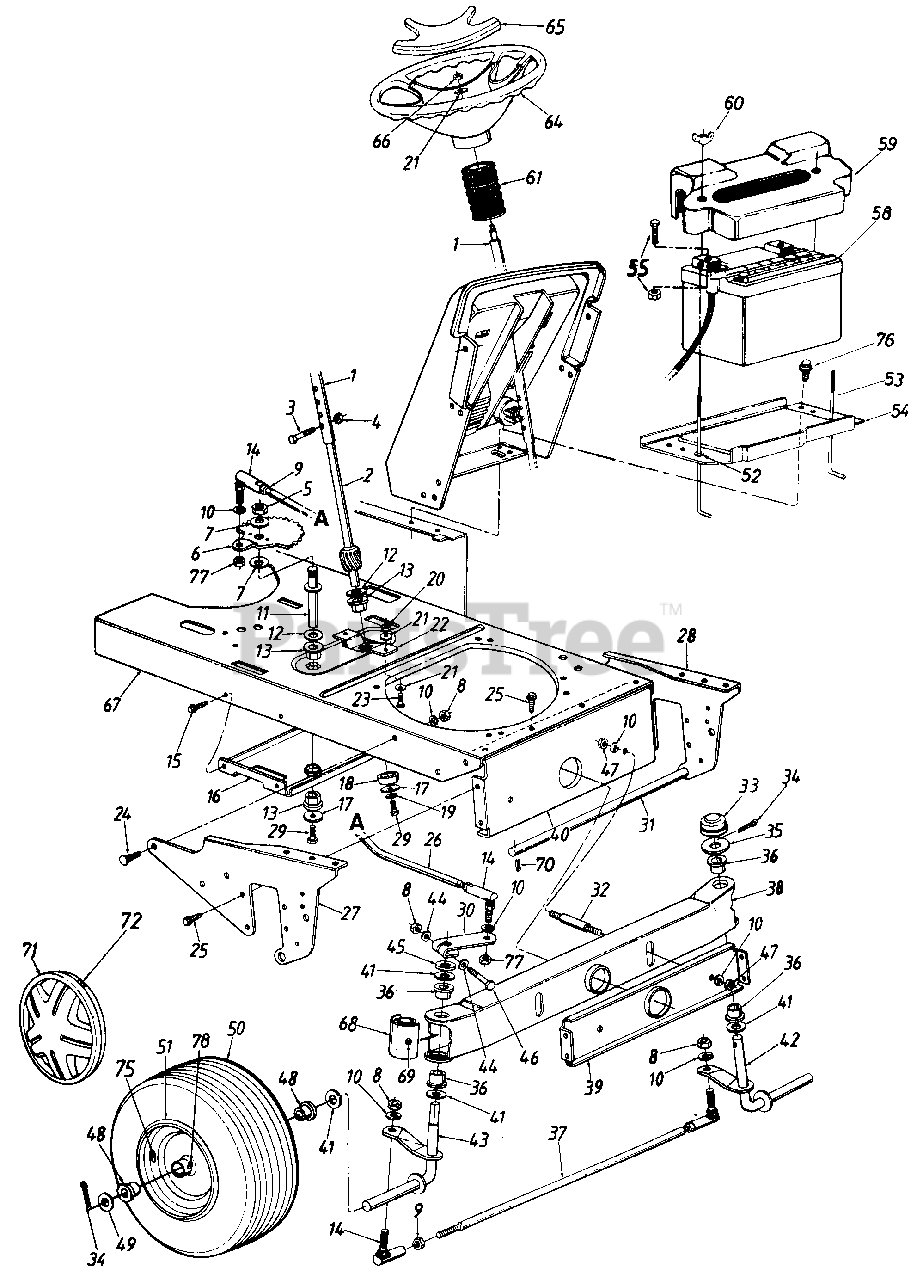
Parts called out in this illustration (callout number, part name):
1	Steering Column Ass'y.
2	Lower Steering Shaft
3	Hex Bolt 1/4-20 x 1.31" Lg.
4	Hex L-Nut 1/4-20 Thd.
5	Hex Nut 5/8-18 Thd.
6	Steering Gear Segment
7	Bell-Wash. 5/8" I.D. x 1.25" O.D.
8	Hex Nut 3/8-24 Thd.
9	Hex Jam Nut 3/8-24 Thd.
10	L-Wash. 3/8" I.D.
11	Steering Gear Segment Shaft
12	Fl-Wash. .64" I.D. x 1.24" O.D.
13	Hex Flange Brg. .63" I.D.
14	Ball Joint Ass'y.
15	Hex Wash. Hd. TT-Tap Scr. 1/4-20 x .5" Lg.
16	Deck Idler Support Brkt.
17	Fl-Wash. .33" I.D. x 1.25" O.D.
18	Spacer .985" I.D. x 1.25" O.D.
19	L-Wash. 5/16" I.D.
20	Hex Nut 5/16-24 Thd.
21	Bell-Wash. .345" I.D. x .88" O.D.
24	Ribbed Neck Bolt 3/8-24 x .8" Lg.
25	Hex Wash. TT-Tap Scr. 5/16-18 x .62" Lg.
26	Steering Drag Link
27	Pivot Bar Side Plate - R.H.
28	Pivot Bar Side Plate - L.H.
29	Hex Bolt 5/16-18 x .62" Lg.
30	Steering Arm
31	Deck Connecting Rod
32	Pivot Bar Shld. Bolt 3/8-16 x 5/8" Lg.
33	Cap
34	Cotter Pin 5/32" Dia.
36	Flange Brg. .757" I.D.
37	Tie Rod 20.25" Lg.
38	Pivot Bar Assy.
41	Fl-Wash. .76" I.D. x 1.49" O.D.
42	Front Axle Ass'y. - L.H.
43	Front Axle Ass'y. - R.H.
44	Bowed Washer
45	Spacer .755" I.D. x 1.25" O.D.
46	Hex Bolt 3/8-24 x 2.25" Lg.
47	Hex Nut 3/8-16 Thd.
48	Ball Brg. .75" I.D.
49	Fl-Wash. .71" I.D. x 1.5" O.D.
51	Rim Only
52	Push Nut
53	Battery Hold Down Rod
54	Battery Plate
55	Comes w/Battery
58	Battery (275 Cold Crank Amps)
59	Battery Cover
60	Wing Nut Plastic 1/4-20 Thd.
61	Steering Bellow
64	Steering Wheel
65	Steering Wheel Cap
66	Hex L-Nut 5/16-24 Thd.
67	Lower Frame
68	Pivot Bar End Cap
69	Grease Fitting
70	Internal Cotter Pin
71	Hub Cap
72	Spring Clip
75	Air Valve
76	Hex AB-Tap Scr. 1/4 x .62" Lg.
77	Hex Jam L-Nut 3/8-24 Thd.
78	Grease Fitting
